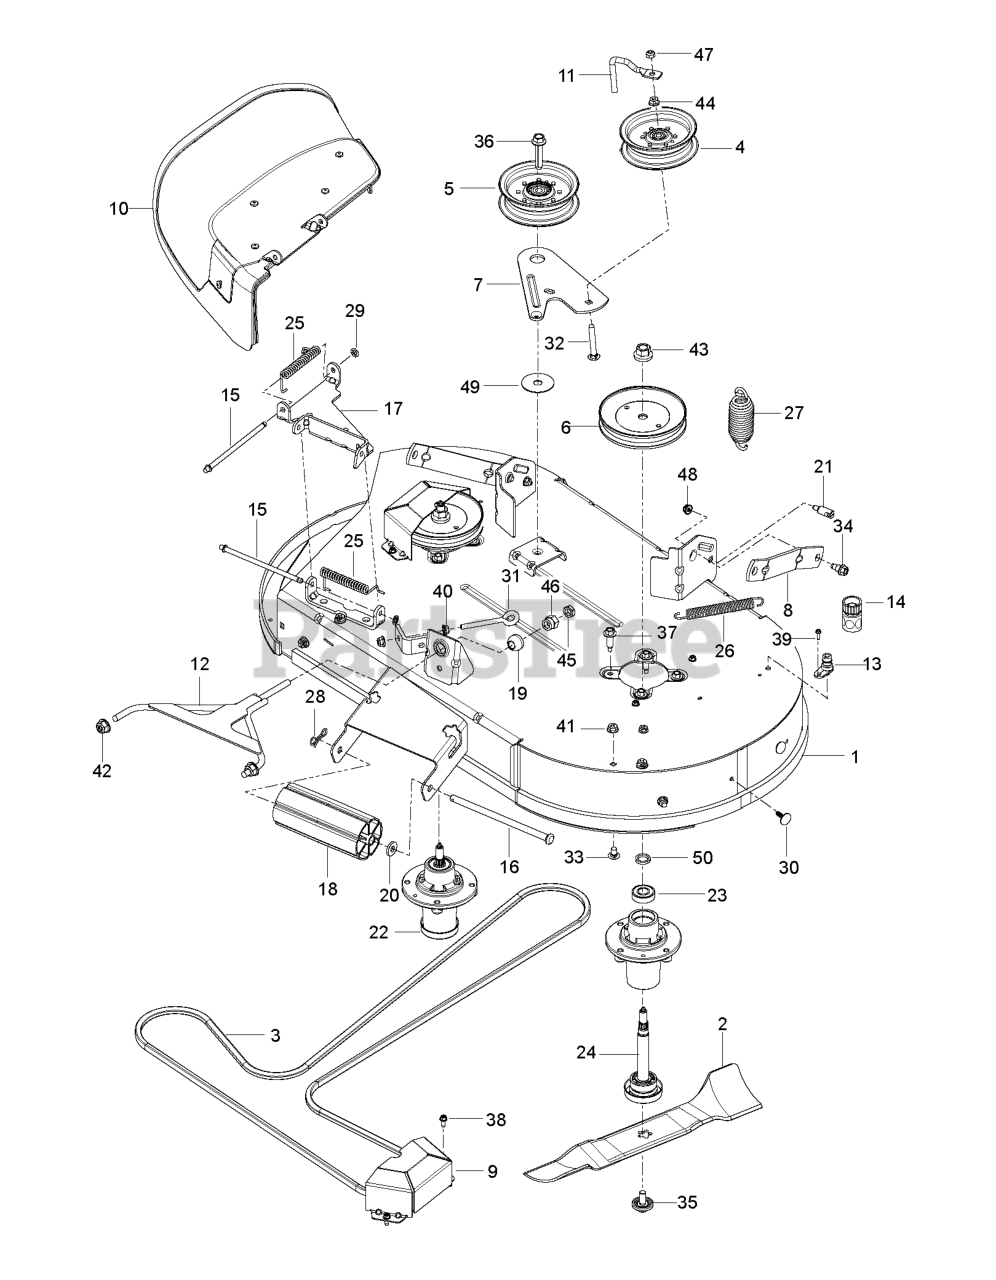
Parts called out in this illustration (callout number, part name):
1	DECK.SVC.42.W/DCLS.CC.RED 667
2	BLADE.42.FCS.BAGGING.BLADE.RAW
3	BELT.42.FCS.ZTR.DECK.DRIVE
4	PULLEY.IDLER.2006
5	PULLEY.IDLER.MWR.STATI.LH
6	PULLEY MANDREL 5.0"
7	ARM.42"FCS.CLUTCHING.X431
8	ARM.RFIXED.MOWER.SUSPNSIONX431
9	COVER 42 FCS MANDREL COVER BLA
10	DEFLECTOR 42 FCS DEFLECTOR ASM
11	KEEPER.BELT.IDLER.54"T
12	LINK.RZ.FRONT.WELDMENT.E-DIP
13	PORT.WASHOUT
14	COUPLING.QUICK CONNECT
15	ROD.HINGE
16	ROD.ROLLER.NOSE.NARROW.48"
17	BRACKET.42'.FCS.DBLE.HINGE.RED
18	NOSE ROLLER 48"
19	BUSHING SPHERICAL SUSP. FRONT
20	BUSHING.NOSE.ROLLER
21	STUD.FASTNER.W/ANTI-ROTATE
22	MANDREL ASM, CAST IRON
24	SHAFT ASM MANDREL
25	SPRING.42.FCS.DEFLECTOR
26	SPRING.MOWER.DRIVE.ELECTRIC
27	SPRING
28	PIN.COTTER.5/16.BOW TI
29	NUT PUSH M
30	FASTENER.XMAS.TREE
31	EYE BOLT 5/16 X 3.50
32	BOLT
33	CARRIAGE BOLT 5/16C X 5/8"
34	BOLT.SHOULDER
35	BOLT.WASHER.ASM.7/16-2
36	SCREW.7/16-14 X 2.125.WASHER
37	BOLT.HEX.WASHR.HED.313-18X1.19
38	SCREW.1/4-20X5/8
39	SCREW HEX CRT
40	NUT 5/16C WHIZ
41	5/16-18 NYLOC FLANGE NUT
42	CLIP NUT.7/16-14.HEX.W/NYLOC
43	NUT.FLANGE.LOCK.TOP
44	LOCKNUT
46	NUT, LIFT LINK 7/16-20
47	NUT LOCK FLG 3/8-16 UNC
48	NUT LOCK HEX FLANGE 5/16-18
50	WASHER.SPACER.MANDREL
